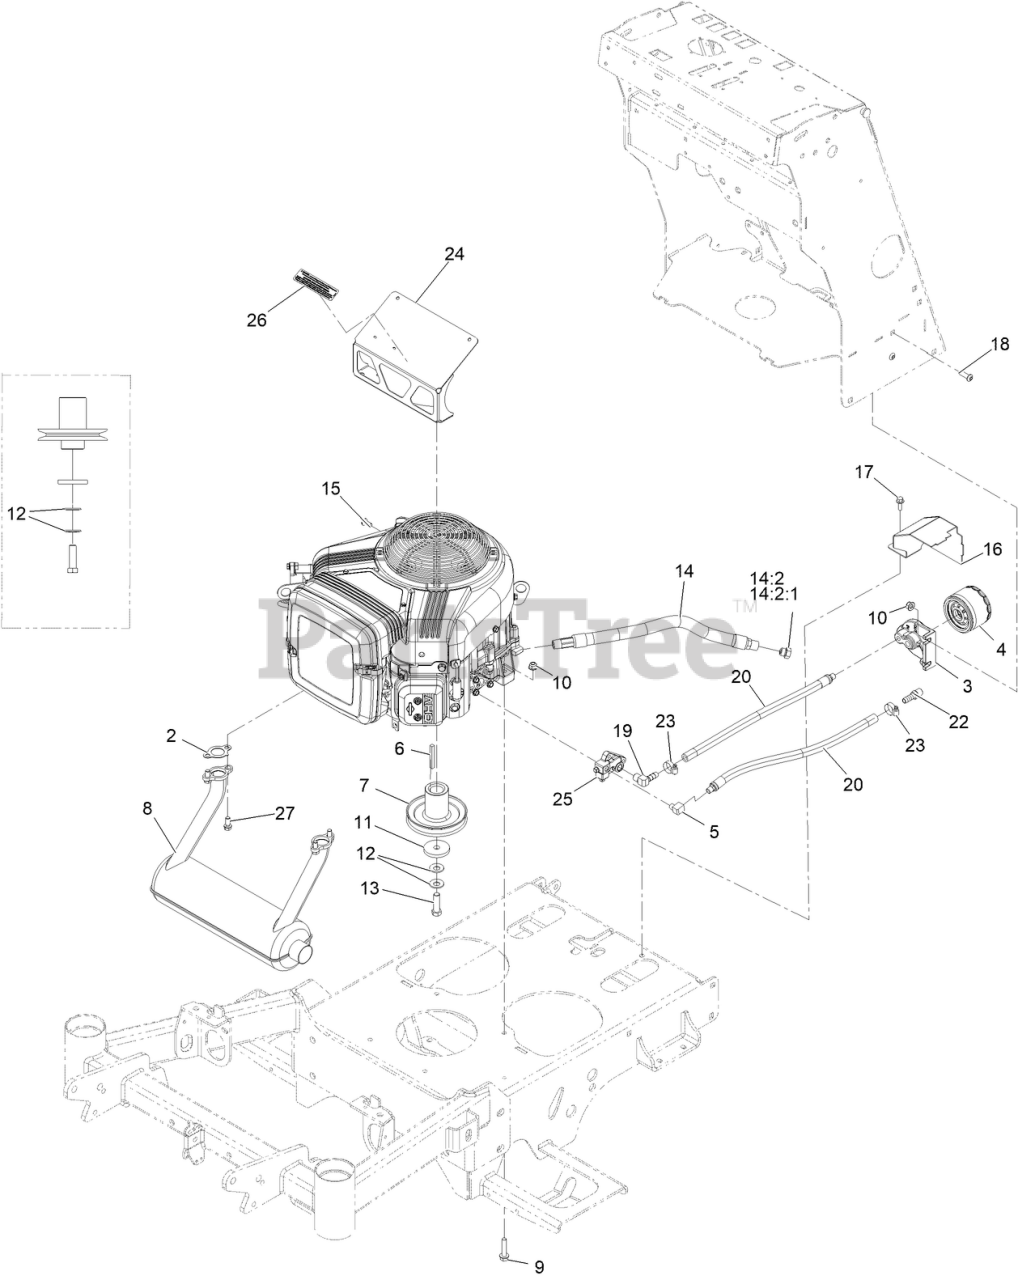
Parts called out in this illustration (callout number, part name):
3	MOUNT-FILTER, REMOTE
4	FILTER-OIL
5	ELBOW-PIPE, 90
7	PULLEY-ENGINE
8	BRIGGS 16/18 HP MUFFLER
9	5/16-18X 1-1/2 HEX FLANGE
10	Nut-Hex Flange
11	WASHER-CLUTCH
12	WASHER-SPRING
13	SCREW-HH 7/16-20 X 1 1/2 W/LOCTITE
14	OIL DRAIN HOSE ASM
14:2	PLUG-HH
14:2:1	O-RING
15	SCREW-BHTORX
16	COVER-FILTER
17	Screw-HHF
18	SCREW-HSBH
19	FITTING-ELBOW, 90
20	HOSE AM, HYD LP
22	FITTING-STRAIGHT
23	CLAMP-HOSE
24	BRACKET-ENGINE
25	ADAPTER-ASM, SERVICE
26	DECAL-ARRESTOR, SPARK
27	SCREW-HSBH
